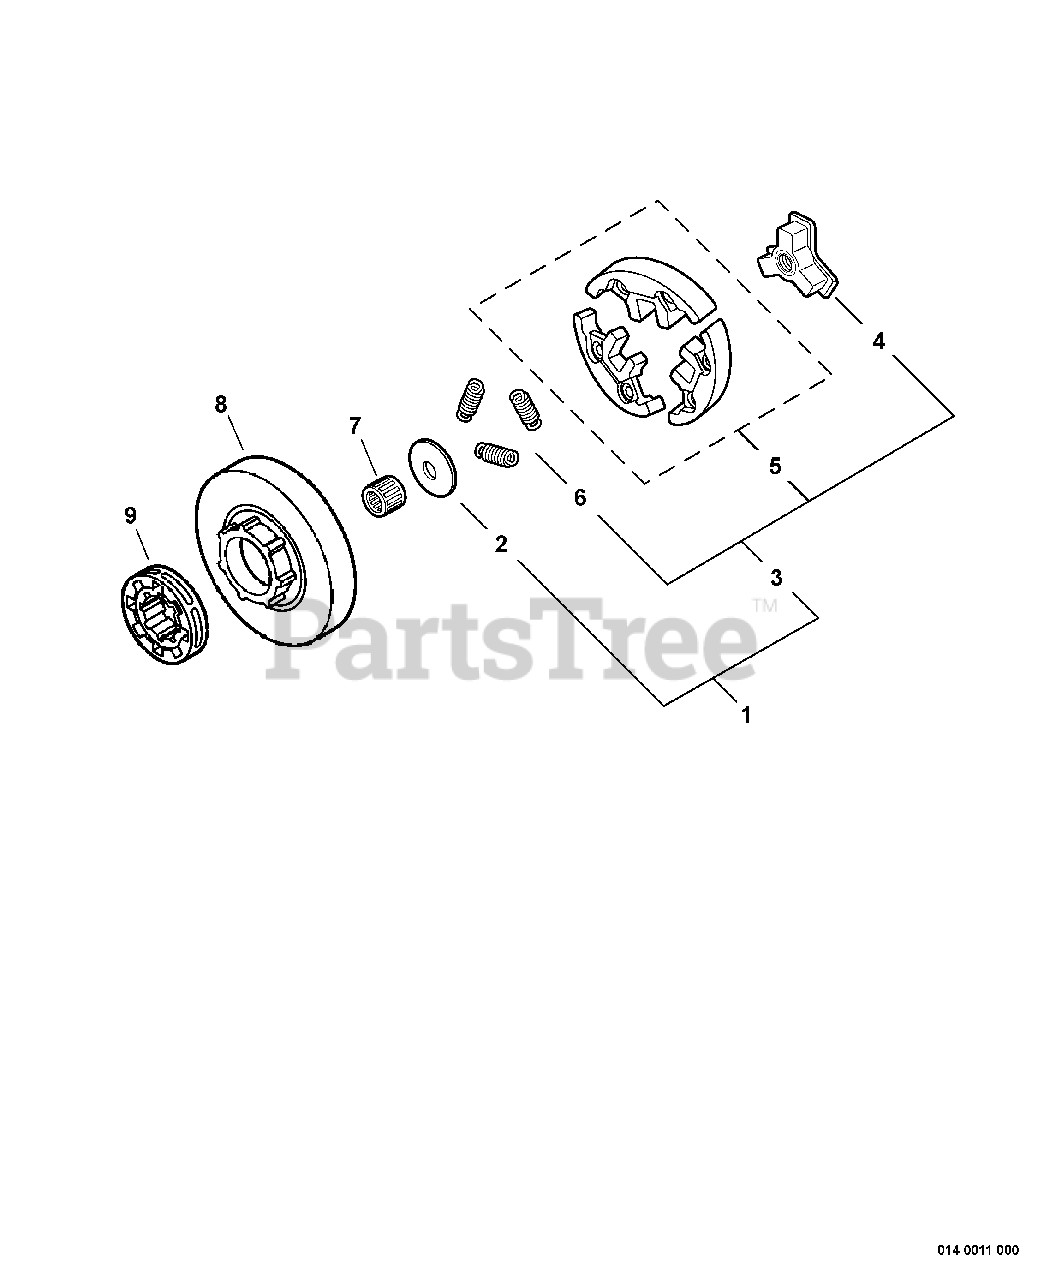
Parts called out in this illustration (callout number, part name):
1	CLUTCH ASSY
2	PLATE, CLUTCH
3	CLUTCH ASSY
4	HUB, CLUTCH
5	CLUTCH SHOE SET
6	SPRING, CLUTCH
7	BEARING, NEEDLE
8	DRUM, CLUTCH
9	SPROCKET, RIM
